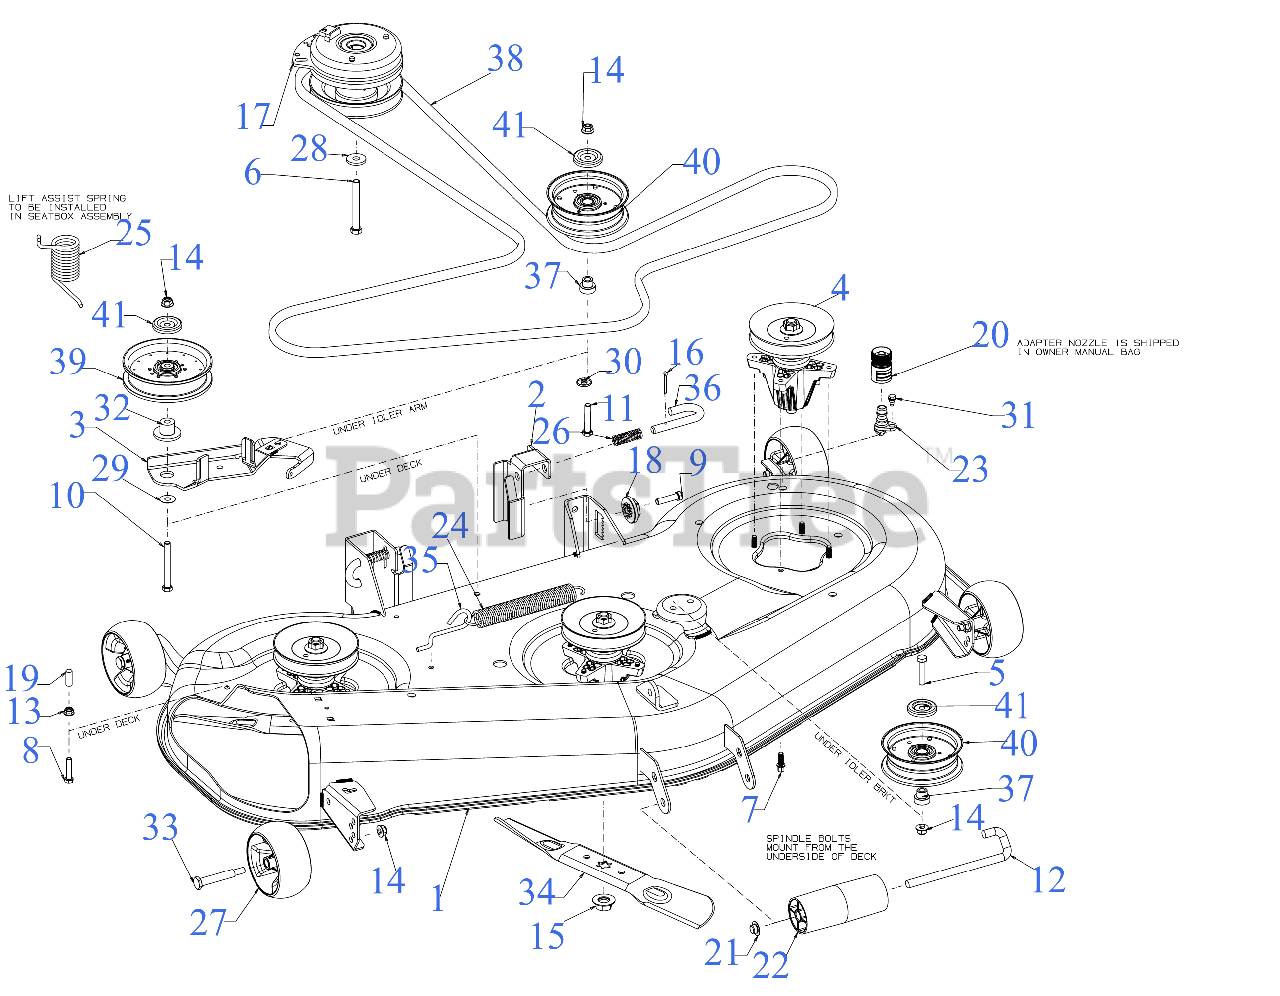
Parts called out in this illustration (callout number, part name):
4	SPINDLE ASSEMBLY
4	Cub Cadet 54" SPINDLE (06978 W/HDW)
5	HEX SCREW 3/8-16 x 1.75 GR5
6	SCREW 7/16-20 x 3.5 GR5
7	SCREW 5/16-18 x .875
8	SCREW 5/16-18 x 1.5 LG
9	SCREW 3/8-16X1.5 GR5
10	SCREW 3/8-16 x 3.25 GR8
11	SCREW 3/8-16 x 2.0 GR5
12	ROLLER PIN 1/2 x 7.31
13	FLANGE LOCK NUT 5/16-18
15	HEX NUT
16	COTTER PIN-5/32 DIA
17	ELECTRIC PTO CLUTCH
18	DECK ADJUSTMENT GEAR
19	VINYL CAP
20	WATER NOZZLE ADAPTER
21	PUSH CAP
23	DECK WASH NOZZLE
24	EXTENSION SPRING
25	TORSION SPRING
26	COMPRESSION SPRING .66 OD x 1
27	DECK WHEEL
27	WHEELS-DELUXE 5"
28	FLAT WASHER .445 x 1.248 x .170
29	FLAT WASHER
30	WASHER
31	SHOULDER SCREW 1/4-20 x .50
32	SHOULDER SPACER
33	SHOULDER BOLT .50 x 2.5 x 3/8 -16
34	18.61" BLADE (2N1)
34	Cub Cadet 54" HI LIFT BLADE SET
34	Genuine Factory Parts 54" BLADE SET
34	54" 6 PT STAR LOW LIFT/SAND BLADE
34	Cub Cadet 54" LOWLIFT BLADE SET
34	Genuine Factory Parts 54" LOWLIFT BLADE SET
34	54" 6 PT STAR XTREME MULCH BLADE
34	Cub Cadet 54" XTREME BLADE SET
34	Genuine Factory Parts 54" XTREME MULCH BLADE SET
35	DECK SPRING HOOK
36	DECK RELEASE PIN
37	SHOULDER SPACER
38	V-BELT B SEC x 148.25
38	Cub Cadet 54" DECK DRIVE BELT
38	Troy-Bilt 54" DECK DRIVE BELT
39	FLAT IDLER PULLEY
40	IDLER PULLEY 4.50" DIA
41	IDLER PULLEY CAP
